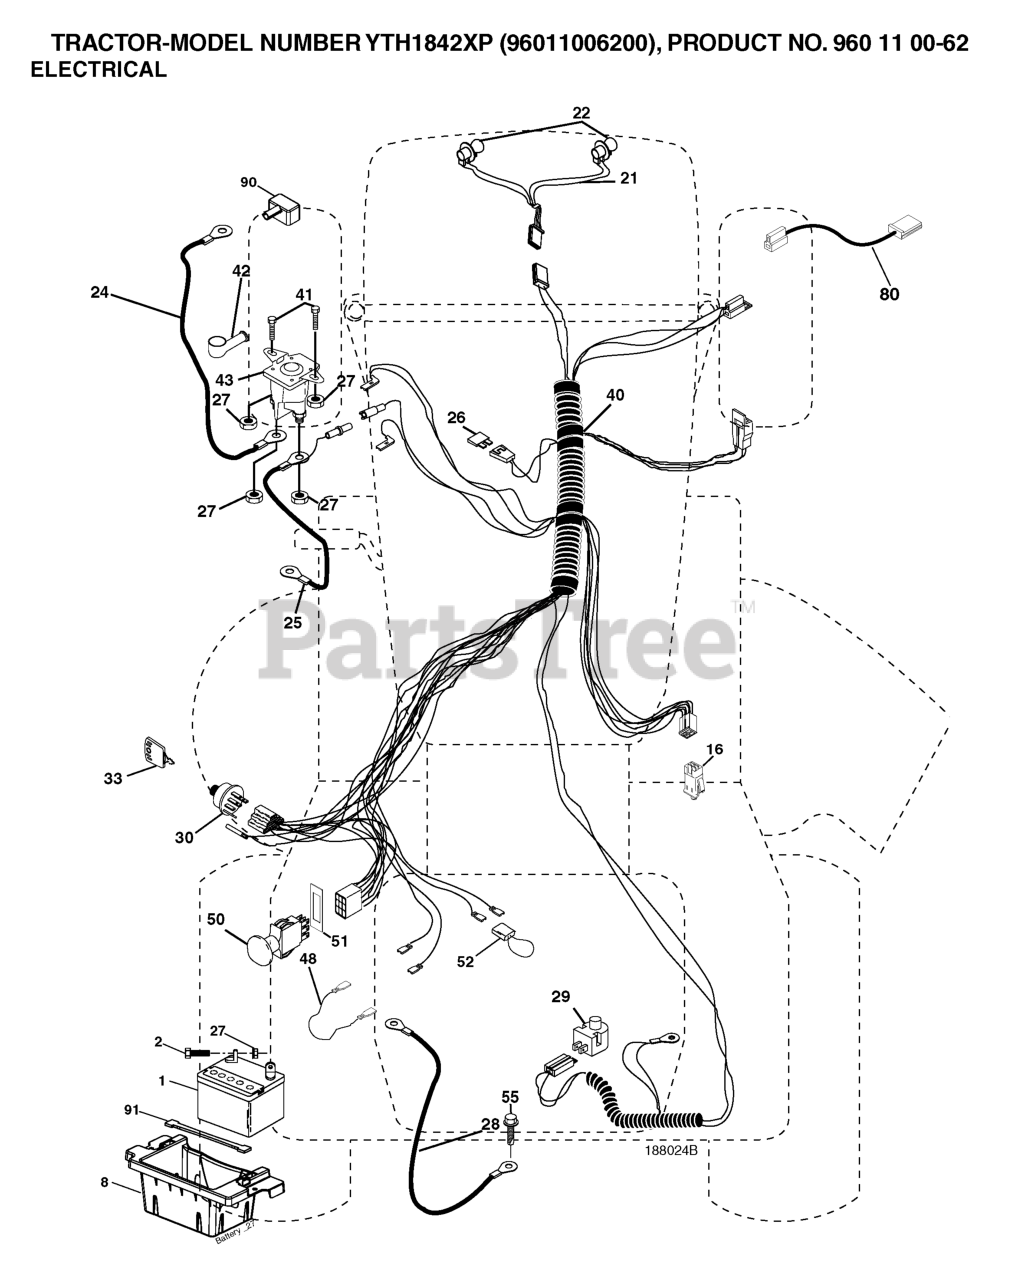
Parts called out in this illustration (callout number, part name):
1	BATTERY 12V .35 AMP
2	BOLT.HEX.1/4.X.3/4.DICHROMATE
8	BOX.BATTERY.MOUNT.FRONT.LT
16	SWITCH INTERLOOK PUSH-IN
21	HARNESS.W/LIGHT SOCKET
24	BATTERY CABLE GT
25	CABLE BATTERY 6 GA 22" W/16W
26	FUSE 20AMP
27	NUT
28	CABLE GROUND 6 GA 21" 90T BLK
29	RP.SWITCH.PLUNGER.NC.GRAY
30	IGNITION SWITCH
33	KEY MLD GEN DELTA
40	HARNESS.IGNITION
41	BOLT
42	TERMINAL COVER
43	SOLENOID
48	ADAPTER.AMMETER
50	RP.PTO.SWITCH.8 TERMINAL.BLACK
51	FRAME RETAINING RING
52	WIRE PROTECTION LOOP
55	Screw 5/16-18 x 1/2 Hex, Self Tapping 5/16-18 x 1/2
80	HARNESS, CLUTCH
90	COVER TERMINAL
91	STRAP.BATTERY.MOUNT.FRONT(2 2)
